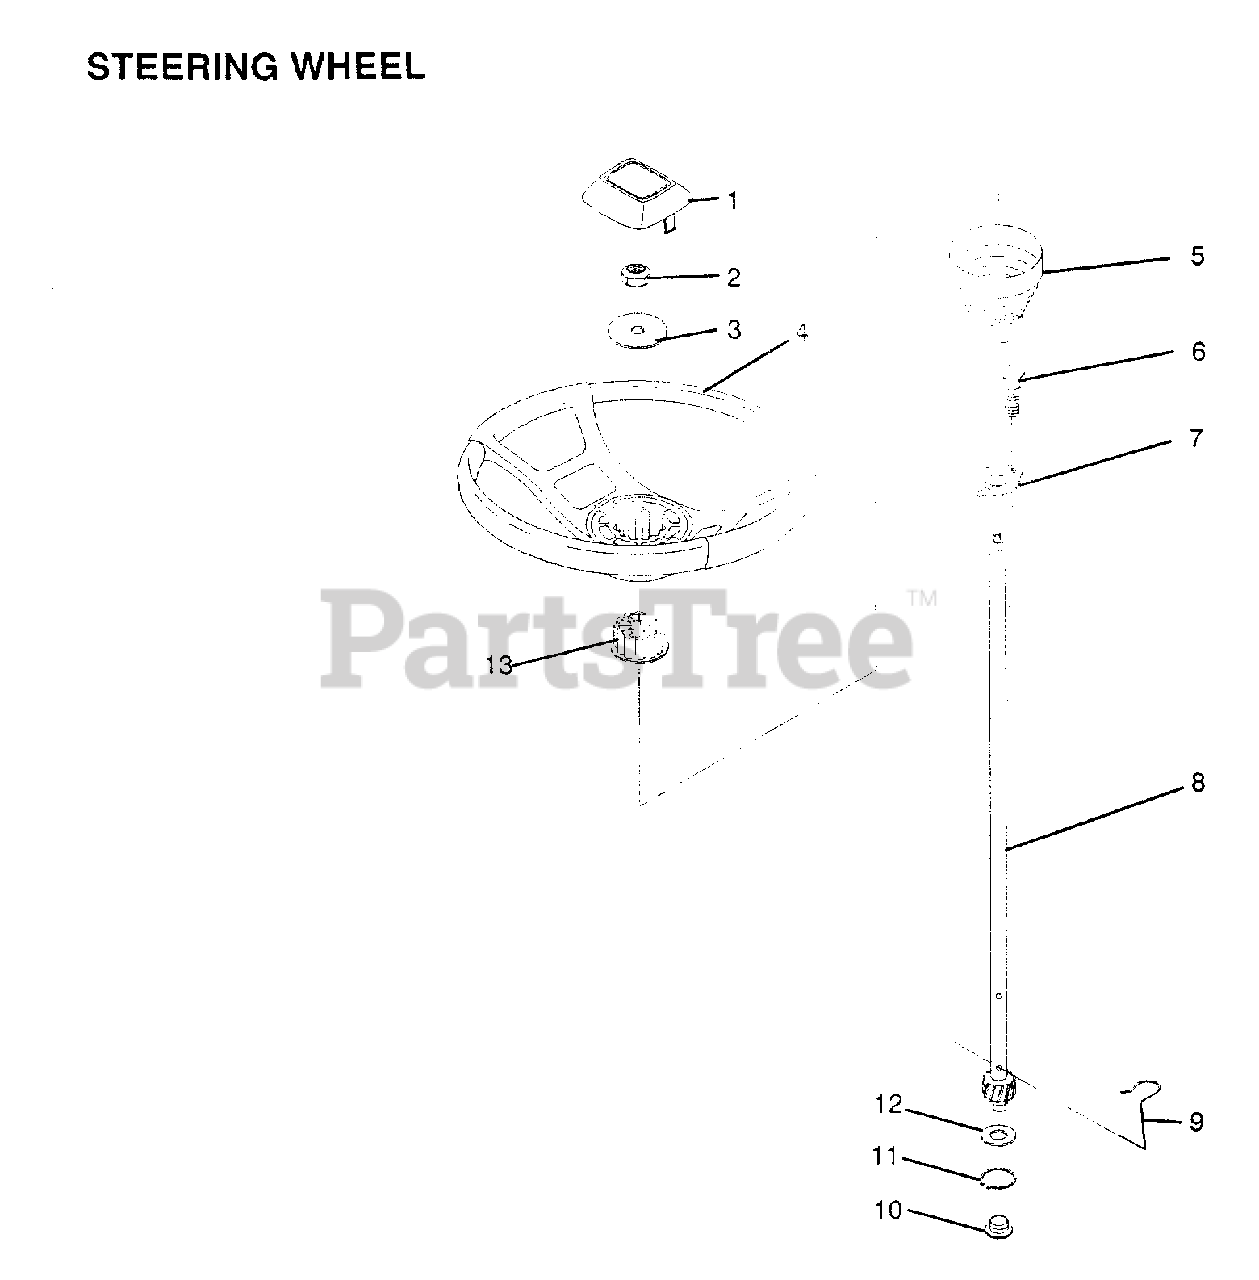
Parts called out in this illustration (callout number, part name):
1	INSERT-WHEEL LT
2	GRIPCO NUT
3	WASHER T
5	SLEEVE STEERING
9	STEERING CLIP
10	BUSHING STEER LWR
11	RING
12	WASHER LT
13	ADAPTER-WHEEL LT
